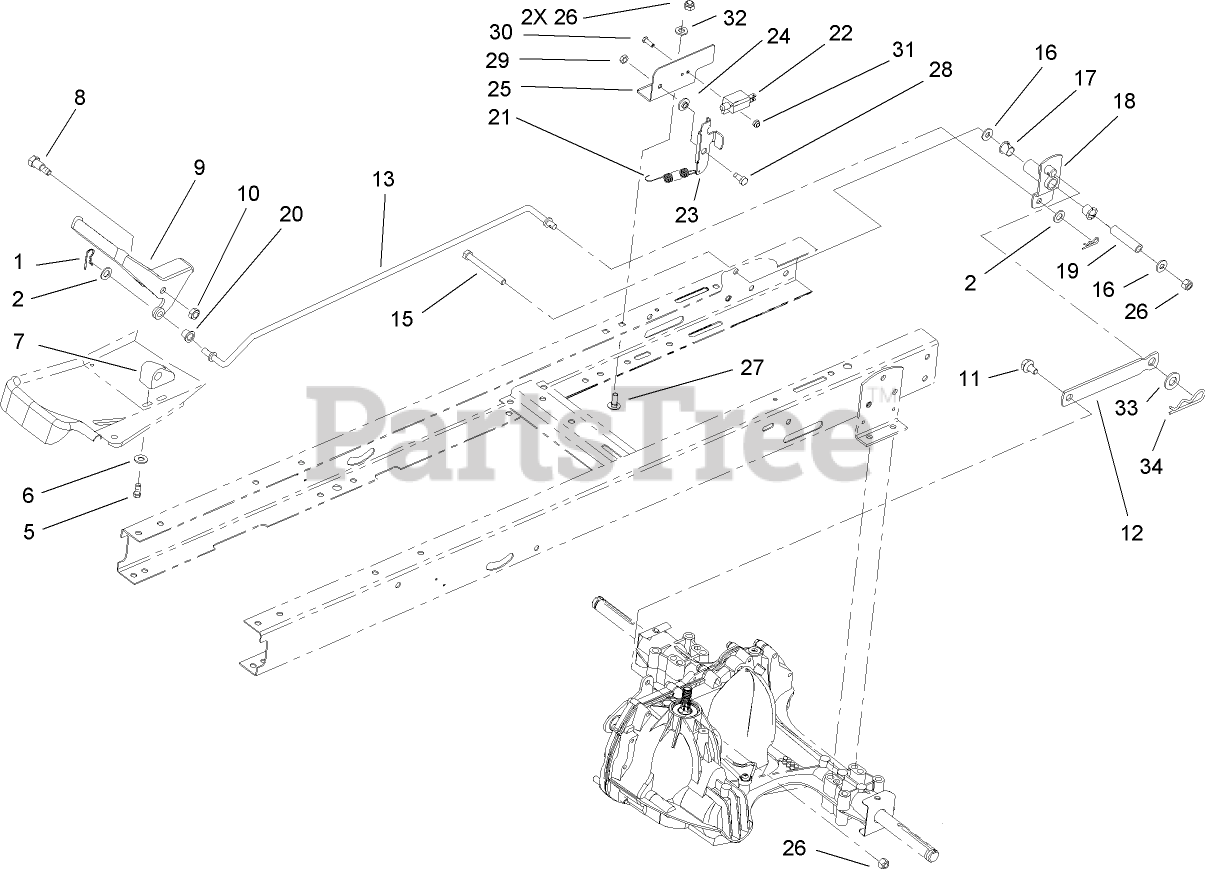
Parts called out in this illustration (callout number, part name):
2	WASHER-FLAT
5	SCREW-PLASTITE
6	WASHER-FLAT
7	BLOCK-PIVOT
8	SCREW-SHOULDER, HH
9	PEDAL-CONTROL, SPEED
11	BOLT-SHOULDER
12	LINK-CONTROL, SPEED
13	ROD-CONTROL, SPEED
15	SCREW-HH
16	WASHER-FLAT
17	BUSHING-NYLINER
18	PIVOT ASM
19	SPACER-PIVOT
20	BUSHING-FLANGED
21	SPRING-EXTENSION
22	SWITCH-POLE, SINGLE
23	BRACKET-PIVOT
24	WASHER-STEPPED
25	BRACKET-ADJUSTMENT
26	NUT-LOCK, NI
27	SCREW-CARR
28	SCREW-HHF
29	NUT-LOCK, NI
30	SCREW-SHH
31	NUT-LOCK
32	WASHER-PLAIN
33	WASHER-FLAT
34	PIN-HAIR
